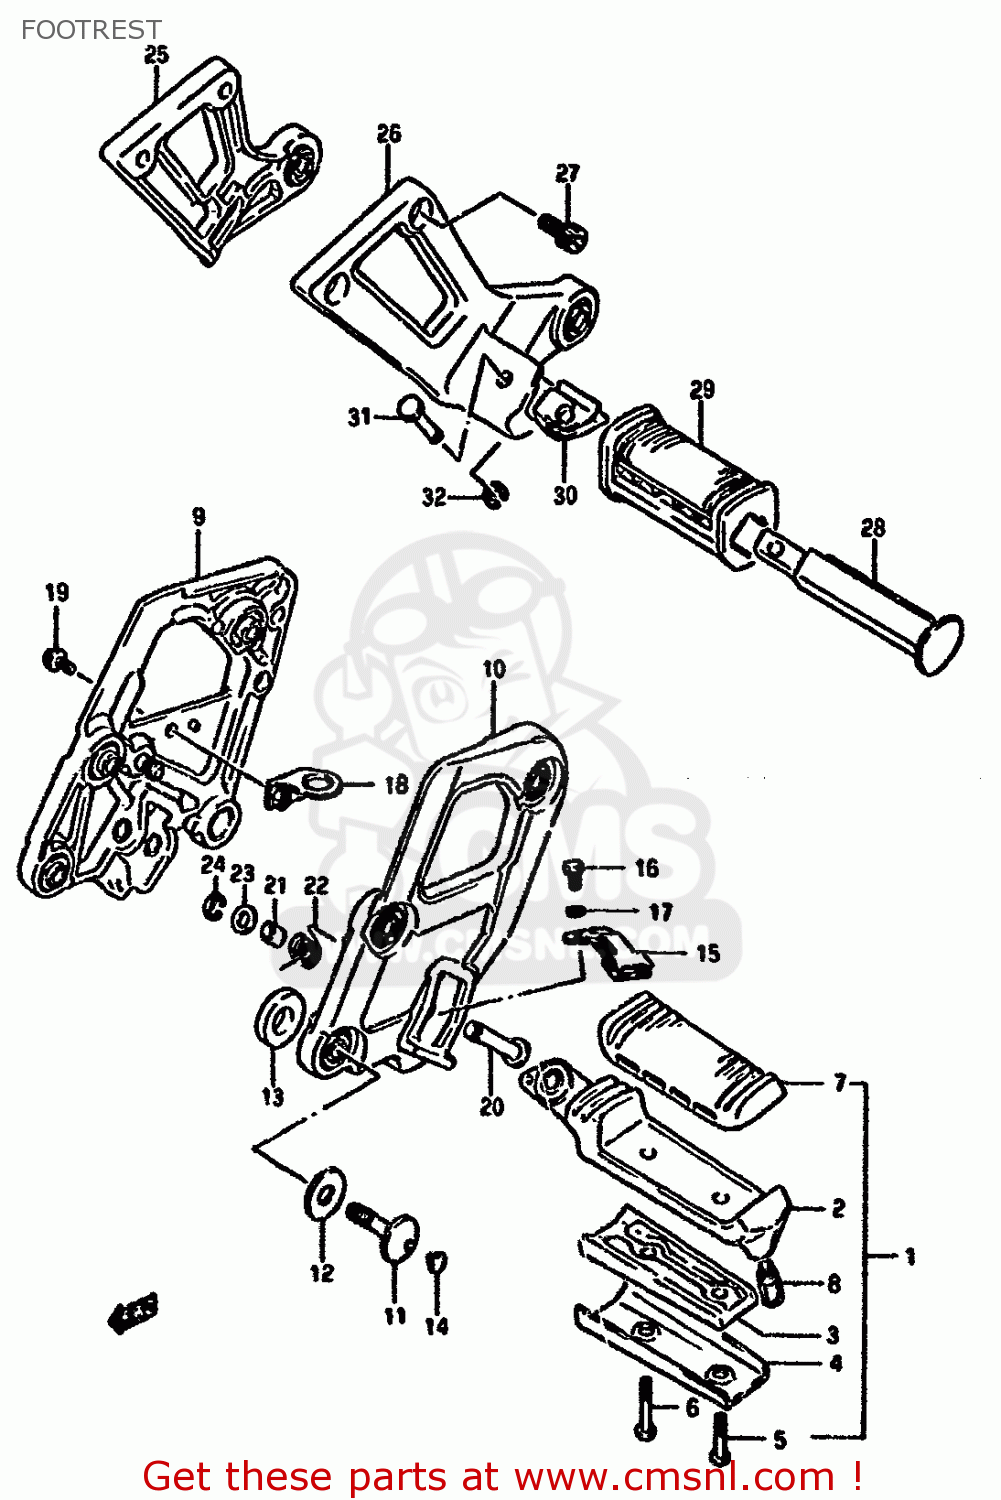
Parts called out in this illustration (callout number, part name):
1	FOOTREST ASSY,FR,R
2	BAR,FRONT FOOTREST
3	BAR,FR FOOTREST NO.2
4	COVER,FRONT FOOTREST B
5	SCREW
6	SCREW
7	RUBBER,FR FOOTREST
8	SENSOR,FOOTREST
9	BRACKET,FR FOOTREST,R
10	BRACKET,FR FOOTREST,L
11	BOLT L:30
12	WASHER
13	WASHER(12X28X5)
14	CAP(OD:10)
15	CUSHION,FR FOOTREST
16	BOLT 5X10
17	LOCK WASHER
18	BRACKET COMP,STOP LAMP SWITCH
19	SCREW(5X10)
20	PIN
21	BUSHING
22	SPRING
23	WASHER
24	E RING
25	BRACKET,PILLION FOOTREST,R
26	BRACKET,PILLION FOOTREST,L
27	BOLT
28	BAR,REAR FOOTREST
29	RUBBER,RR FOOTREST
30	CUSHION,PILLION FOOTREST
31	PIN
32	E RING
